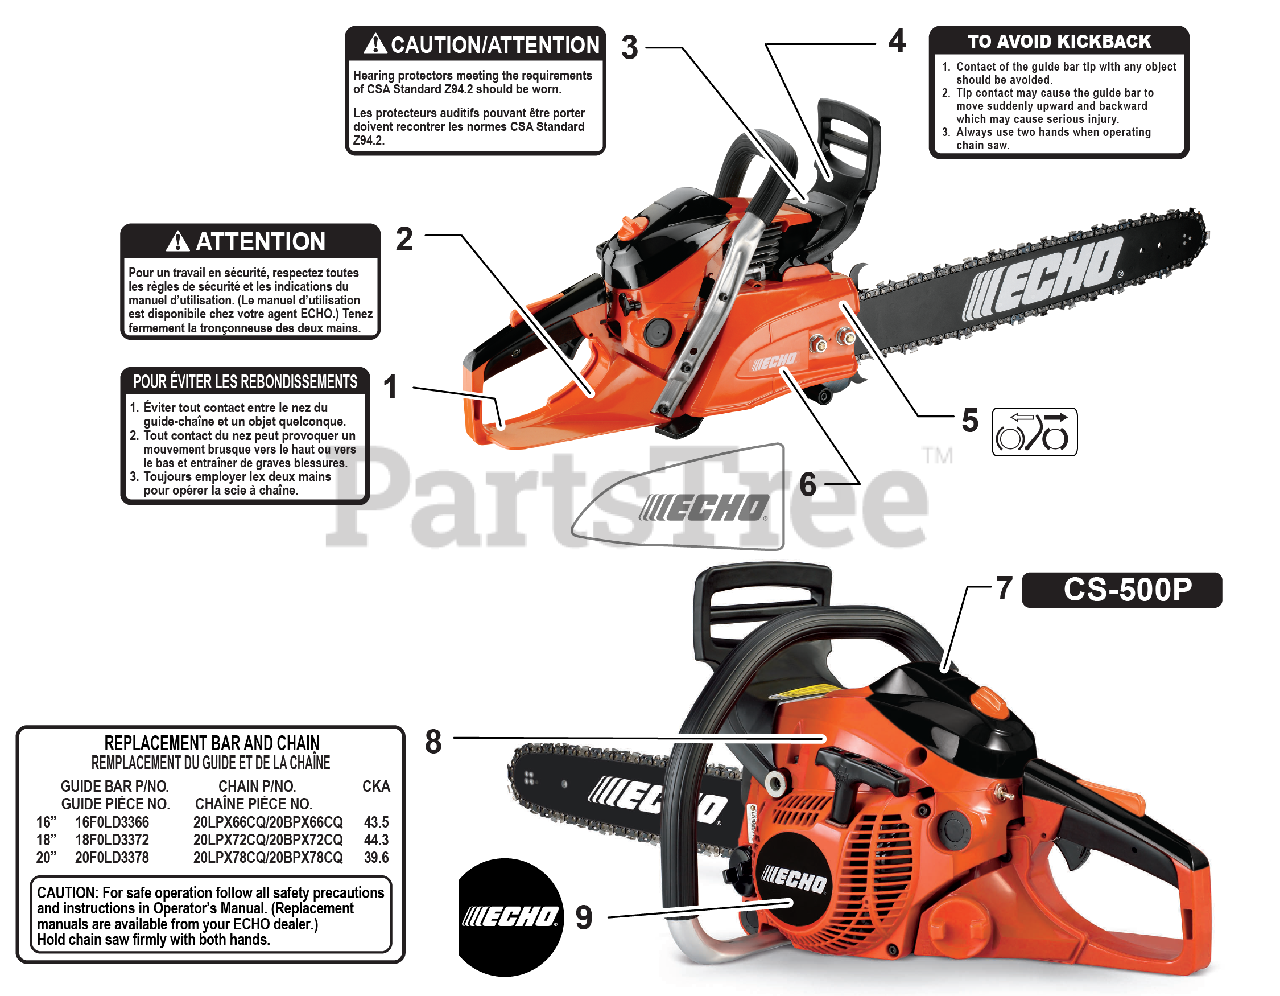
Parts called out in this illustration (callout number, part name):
1	LABEL, KICK BACK - FRENCH
2	LABEL, ATTENTION - CANADA
3	LABEL, NOISE - ENGLISH/FRENCH
4	LABEL, KICK BACK
5	LABEL, CHAIN BRAKE
6	LABEL, ECHO
7	LABEL, CS-500P
8	LABEL, BAR & CHAIN
9	LABEL, ECHO
